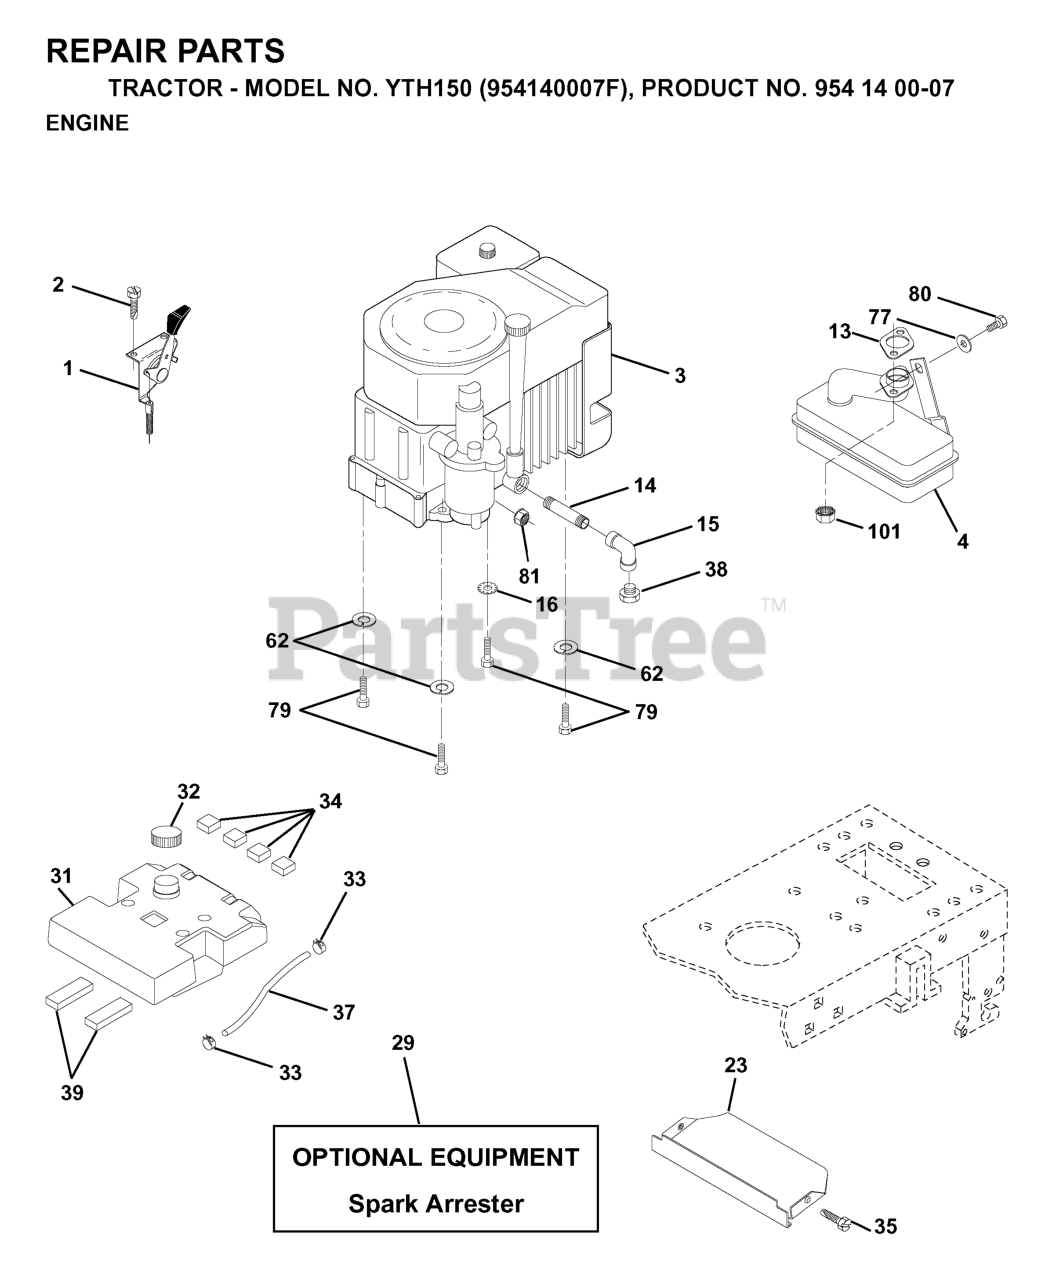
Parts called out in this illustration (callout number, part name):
2	SCREW LT
4	MUFFLER LT 12.5
14	Std. Pipe Nipple 3/8 - 18 NPT x 3 1/2
15	ELBOW
16	WASHER EXT TOOTH LOCK 5/16
29	KIT.SPARK ARRESTOR 794945 B&S
31	TANK.FUEL(3.5.GAL)
32	FUEL CAP
33	HOSE CLAMP
34	PAD-SPACER LT
35	SCREW.THDROL.5/16-18X3/4.TTY
37	HOSE T
39	PAD IDLER TI
62	WASHER.LOCK.HVY.HLCL.SPR.5/16
77	WASHER
79	BOLT, HEX
80	Bolt, Hex Head, Fin. 5/16-18 x 1/2
81	NUT FLANGE 1/4-20 STARTER NUT
101	FLANGE NUT
